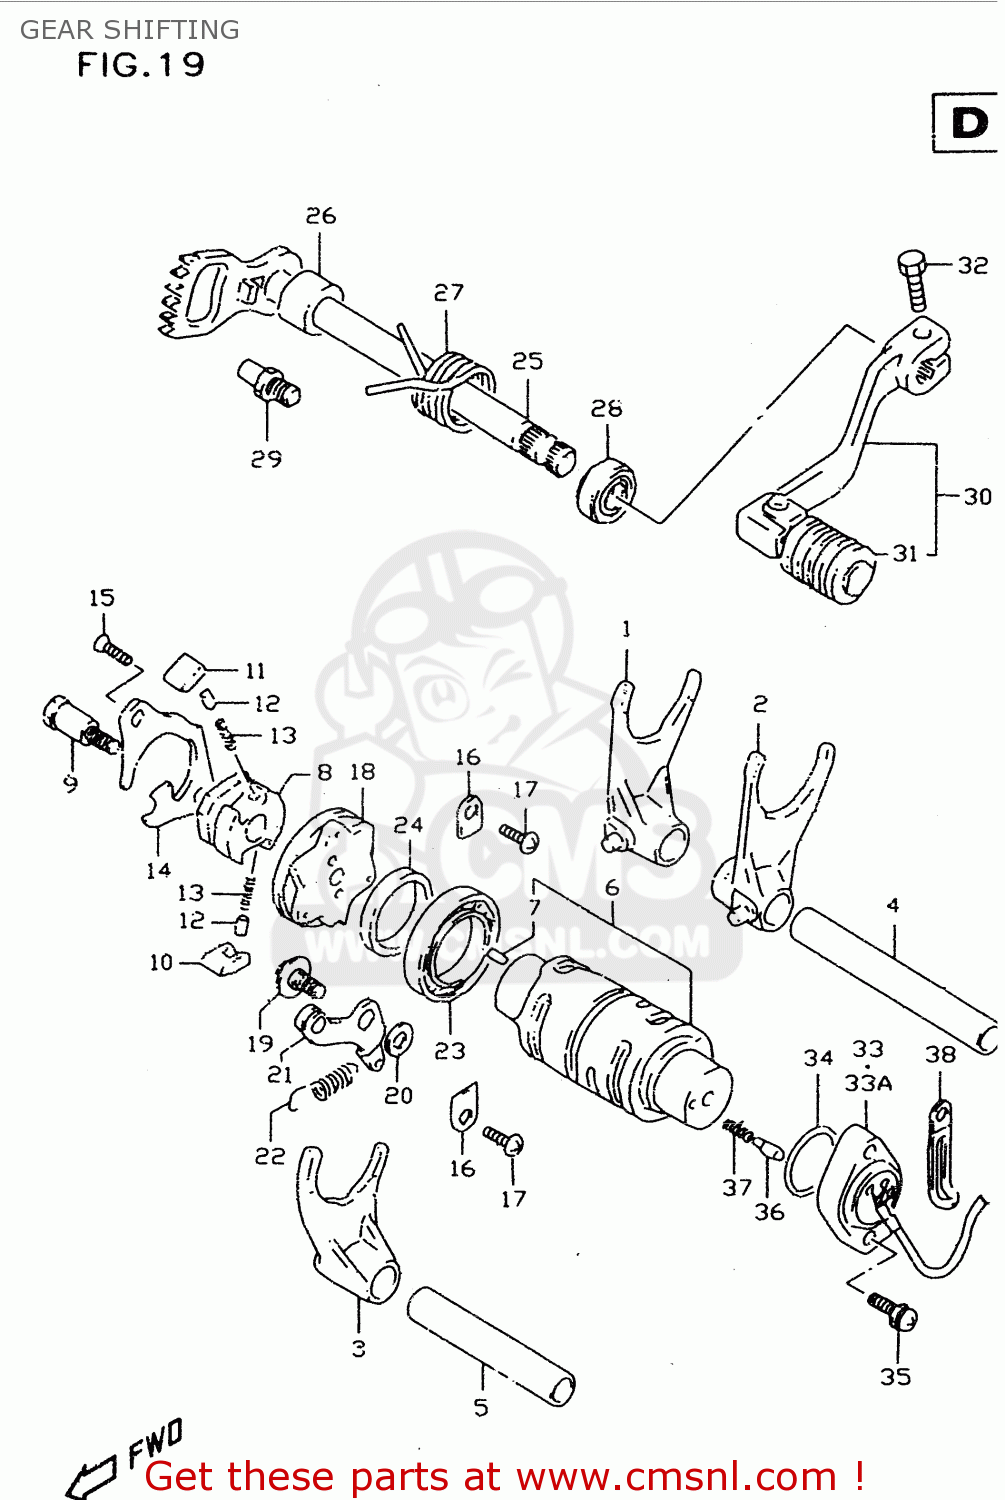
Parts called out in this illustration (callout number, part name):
1	FORK,GEAR SHIFT NO.1
2	FORK,GEAR SHIFT NO.2
3	FORK,GEAR SHIFT NO.3
4	SHAFT,GEAR SHIFT FORK
5	SHAFT,GEAR SHIFT FORK(L:70)
6	CAM,GEAR SHIFT
7	PIN
8	GEAR,GEARSHIFT CAM DRIVE
9	PIN,SHIFT CAM DRIVEN GEAR
10	PAWL,GEAR SHIFT NO.1
11	PAWL,GEAR SHIFT NO.2
12	PIN(5X8)
13	SPRING
14	LIFTER,GEAR SHIFT PAWL
15	SCREW
16	RETAINER
17	SCREW
18	PLATE,GEAR SHIFT CAM
19	BOLT(6X14.3)
20	WASHER
21	STOPPER,GEAR SHIFT CAM
22	SPRING
23	BEARING
24	WASHER(25X32X5.3)
25	SHAFT,GEAR SHIFT
26	SPACER(12X20X15.3)
27	SPRING
28	OIL SEAL
29	STOPPER,GEAR SHIFT ARM
30	LEVER ASSY,GEAR SHIFT
31	RUBBER,GEAR SHIFT PEDAL
32	BOLT
33	BASE ASSY,NEUTRAL SW TERMINAL
33A	BASE ASSY,GEAR SHIFT TERMINAL
34	O RING(D:2.4,ID:26.2)
35	SCREW
36	PIN(5X15.5)
37	SPRING
38	CLAMP
